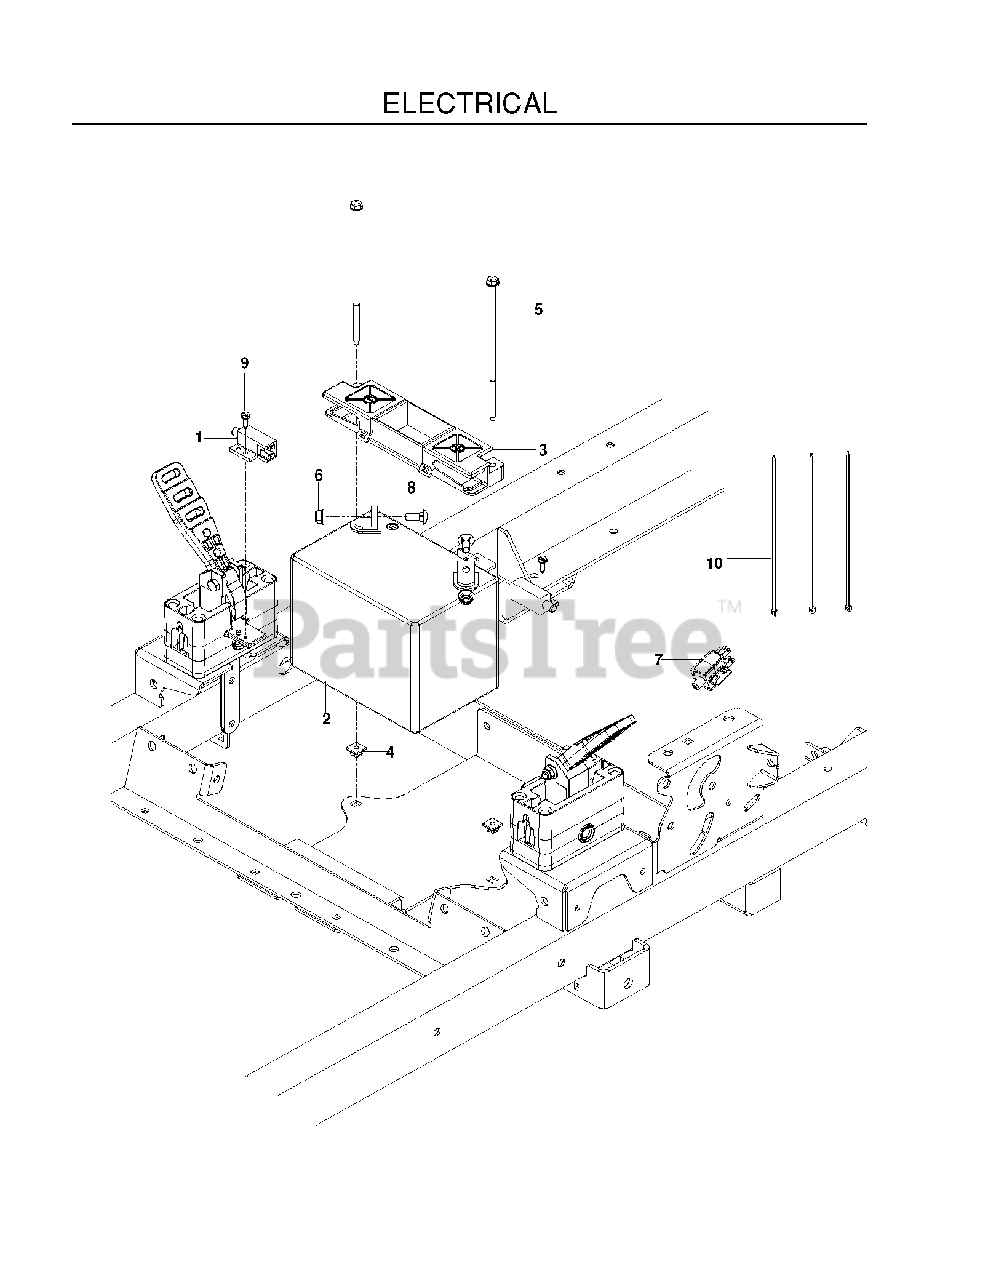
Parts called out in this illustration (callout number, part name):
1	SWITCH, INTERLOCK
2	BATTERY, 12 V 330 AMP
3	BATTERY HOLD DOWN
4	PUSH NUT-NYLON
5	BOLT - 1/4-20 X 7.5
6	5/16-18 NYLOC FLANGE NUT
7	SWITCH, BRAKE 3P
8	BOLT 5/16C X 3/4" CARRIAGE
9	SCREW #10 X 1/2 SELF TAPPING
10	TIE, PLASTIC
